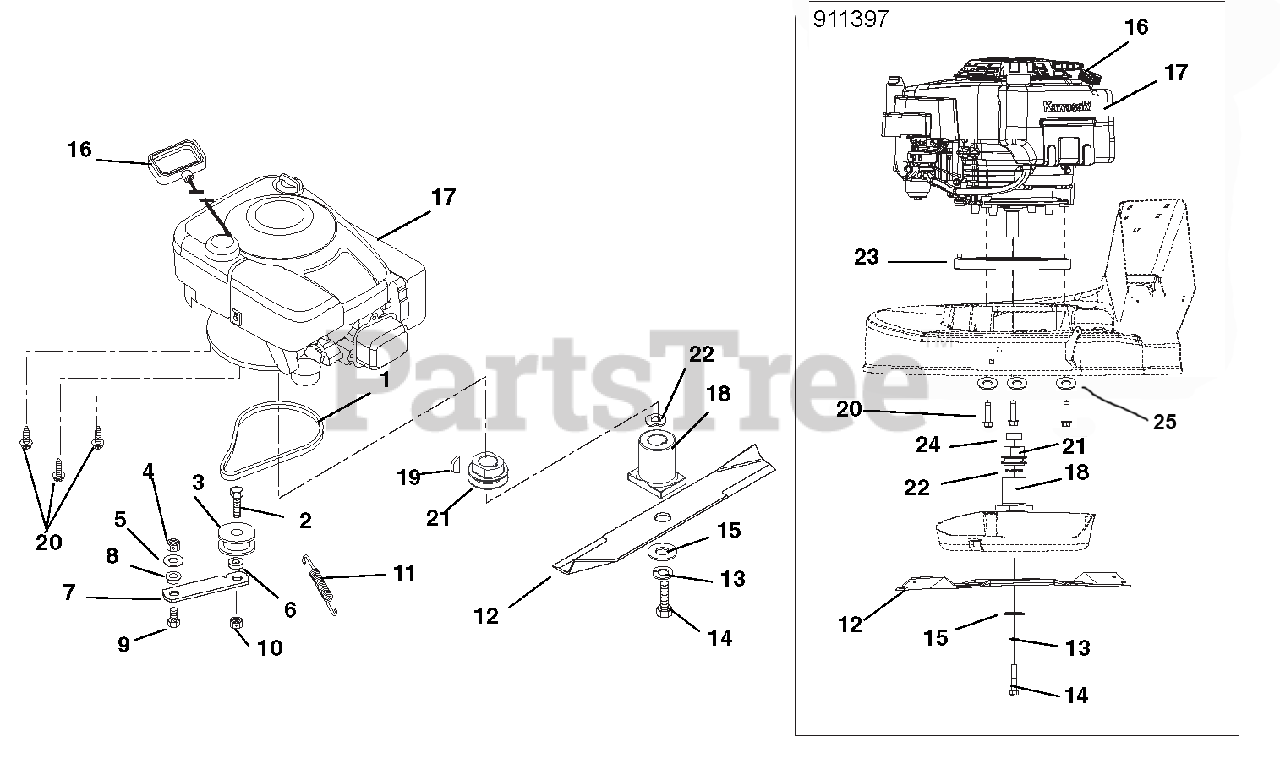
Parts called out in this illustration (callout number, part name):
1	V-BELT, 3L-COGGED
2	@BLT-HEX .44-14X1.50 GR5 YWZC
3	IDLER-FLAT 1.75 X .47
4	@NUT-LK-CTR .31-18 YWZC
5	@WSHR-FL-STL.344X.688X.065YWZC
6	BSHG-SLV .469 X .750 X .430
7	IDLER ARM
8	BSHG-FLG .325X.501X.250X1.120
9	@BLT-HEX .31-18X.75 GR5 YWZC
10	@NUT-LK-CTR .44-14 YWZC
11	SG-TENS .043X.44X3.31 WLD 5.8
12	BLADE, 21" LM MULCHING
13	@WSHR-LK .38X.094 REG YWZC
14	BOLT, 3/8-24X2.5 G8
14	BLT-HEX .38-24 X 2.75 GR8 YWZC
15	WSHR-FL-STL .390X1.5X.125 YWZC
16	HANDLE, RECOIL START
17	B&S - 6.5 HP DOV
17	ENGINE, KAWI FJ180V COMMERCIAL
18	ADAPTER, CE BLADE
18	ADAPTER, BLADE - KAWI KYMCO
19	KEY-WDRF .156X.625X.25 SAE 6
20	@SCR-TAP .38-16X1.00 HWH TR YZ
20	@SCR-TAP .38-16X1.75 HWH TR YZ
21	PULLEY-SINTERED IRON LM
21	PULLEY, CRANK - KAWI KYMCO
22	WASHER-WAVE .885X1.311X.125
23	PLATE, ENGINE SHIM - CAST
24	SPACER, .875 X 1.125 X .525
25	SPACER,.75 X .515 X .12
